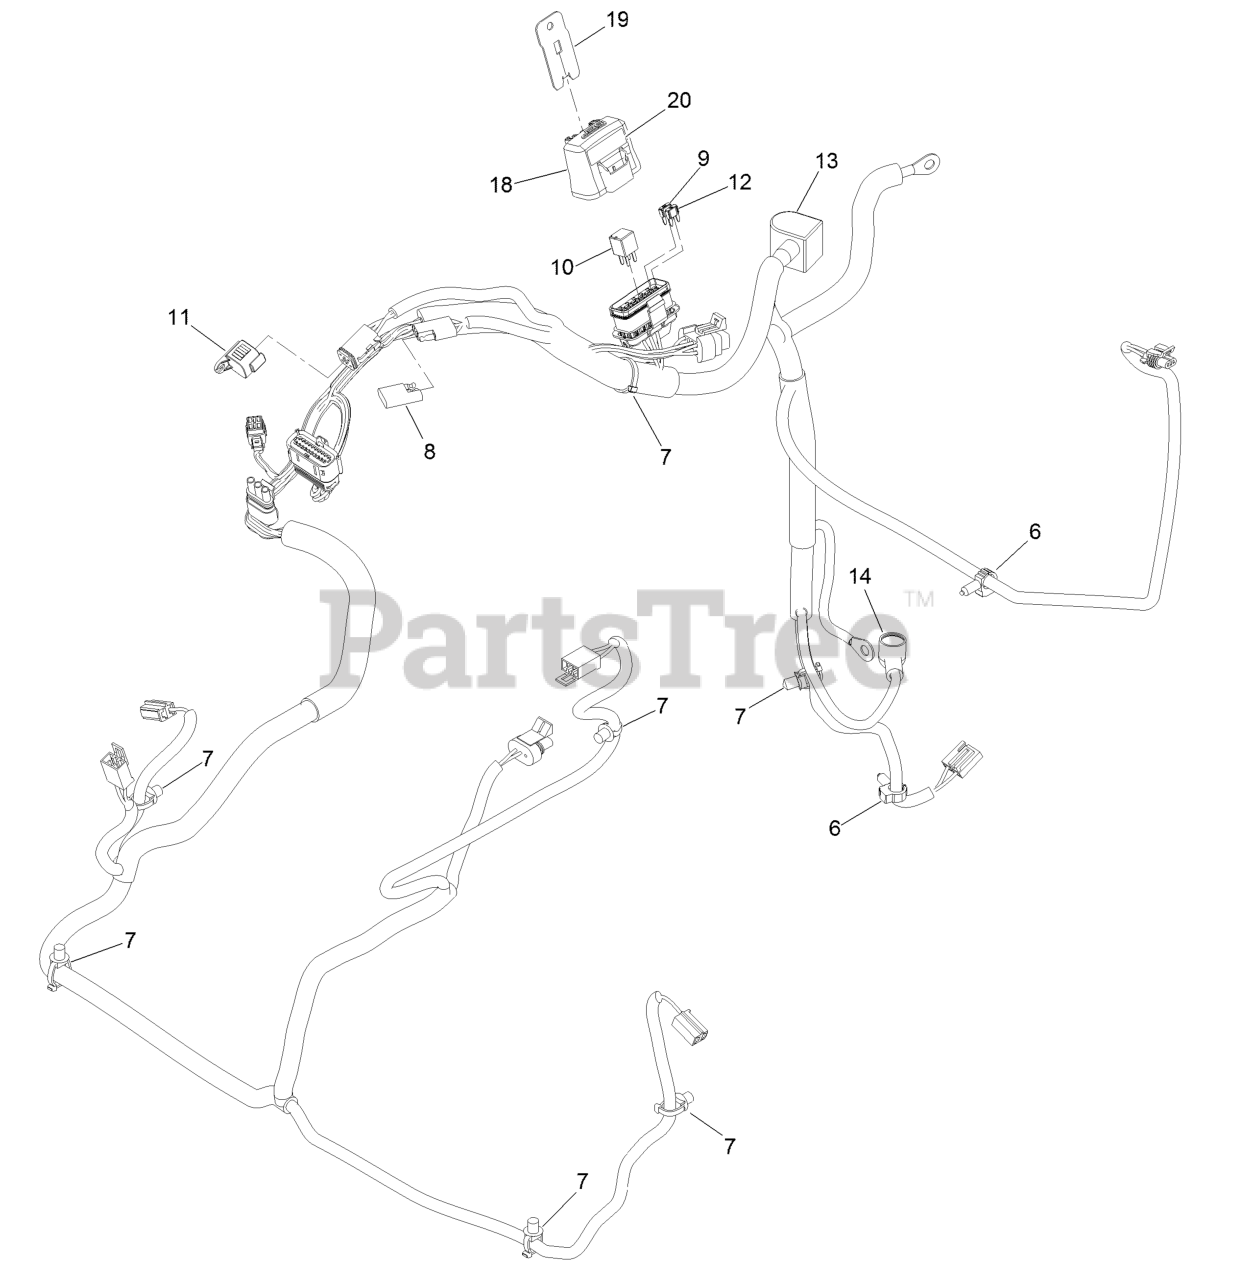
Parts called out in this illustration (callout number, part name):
6	Clip-Harness
7	Clip-Tie
8	Cap-Plug
9	Fuse-Mini Blade, 20 Amp
10	Relay-Micro
11	Cap-Plug, 6 Way
12	Fuse-Mini Blade, 15 Amp
13	Insulator-Battery
14	Insulator-Solenoid
18	Cover-Block, Fuse
19	Clip-Mounting
20	Decal-Fuse
